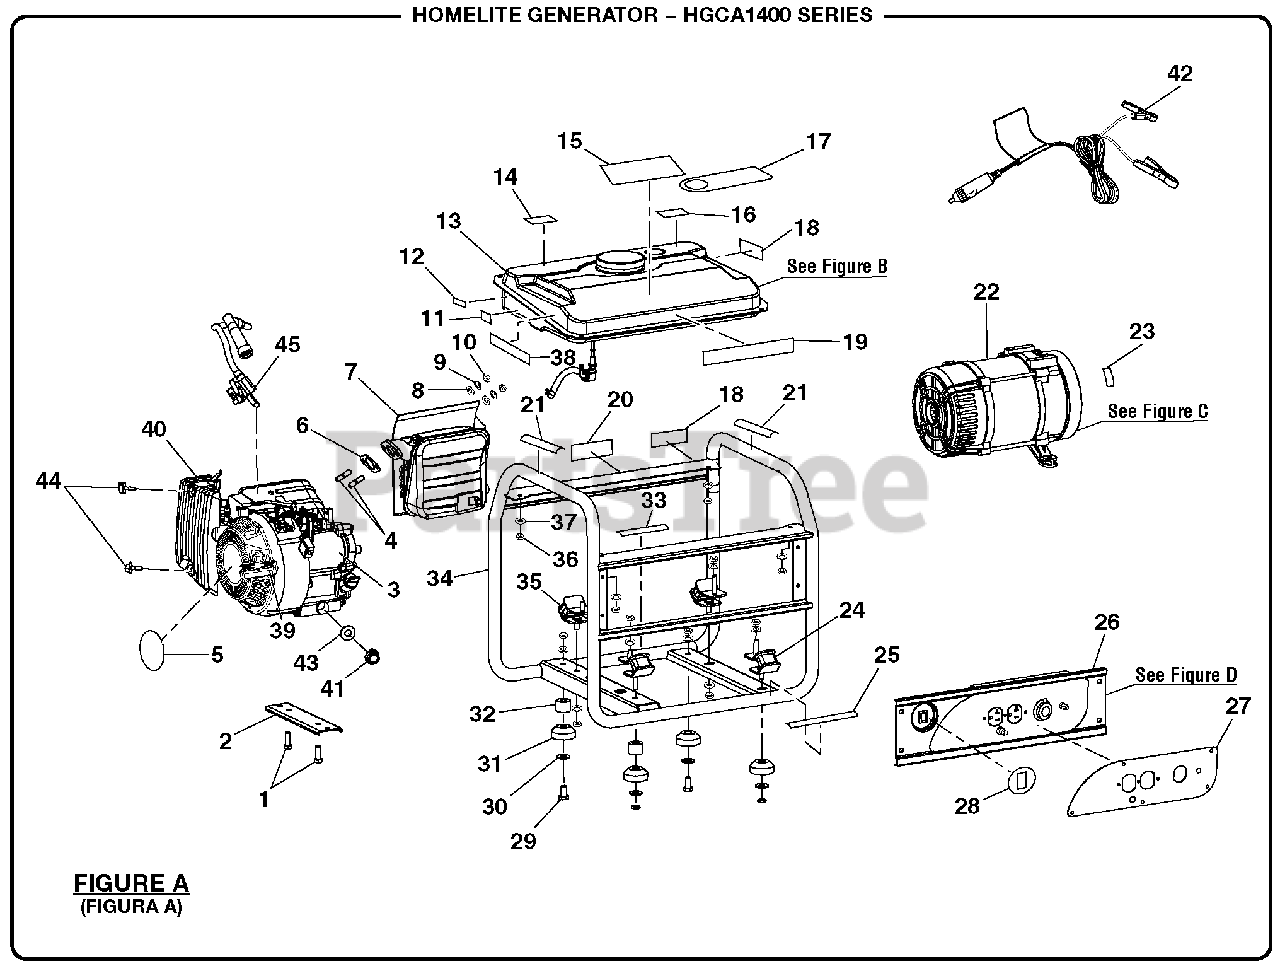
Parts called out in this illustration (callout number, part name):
1	Screw (M8 x 20 mm)
2	Engine Support Bracket
3	Engine (3.0 HP OHV)
4	Exhaust Bolt
5	Recoil Housing Label
6	Exhaust Gasket
8	Washer (M8)
9	Lock Washer (M8)
10	Hex Nut (M8)
11	Choke Label
12	Fuel Valve Label
14	CPSC Label (ENG)
15	Danger Label
16	CPSC Label (FR)
18	Hot Surface Label
19	Logo Label
21	Ground Warning Label
22	Generator Head
23	Ground Icon Label
24	Vibration Absorber (Generator Head Side)
25	Lubricant Warning Label
26	Control Panel
27	Control Panel Label
28	On/Off Label
29	Bolt (M8 x 16 mm)
30	Washer (M8)
31	Rubber Foot
33	UL Warning Label
35	Vibration Absorber (Air Box Side)
36	Lock Nut (M6)
37	Washer (M6)
38	Starting Label
39	Recoil Starter Grip
40	Air Box Cover
41	Oil Drainage Plug
42	Battery Cable Assembly
43	Drain Plug Seal
45	Ignition Coil
